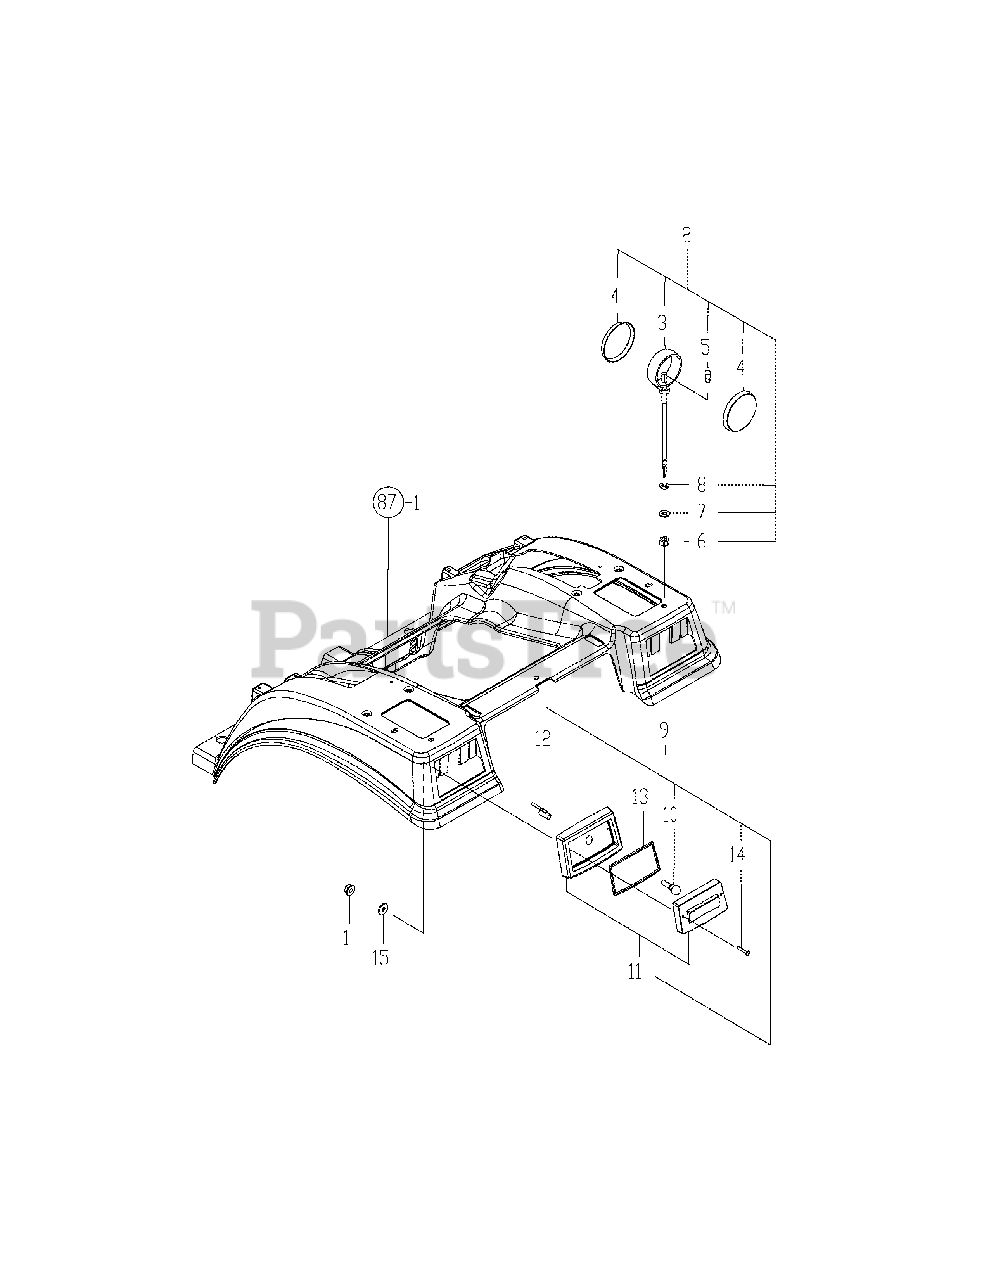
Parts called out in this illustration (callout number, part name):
2	Lamp Assy,Flasher
10	Bulb 12V-21/5W
12	Housing Semi Assy
